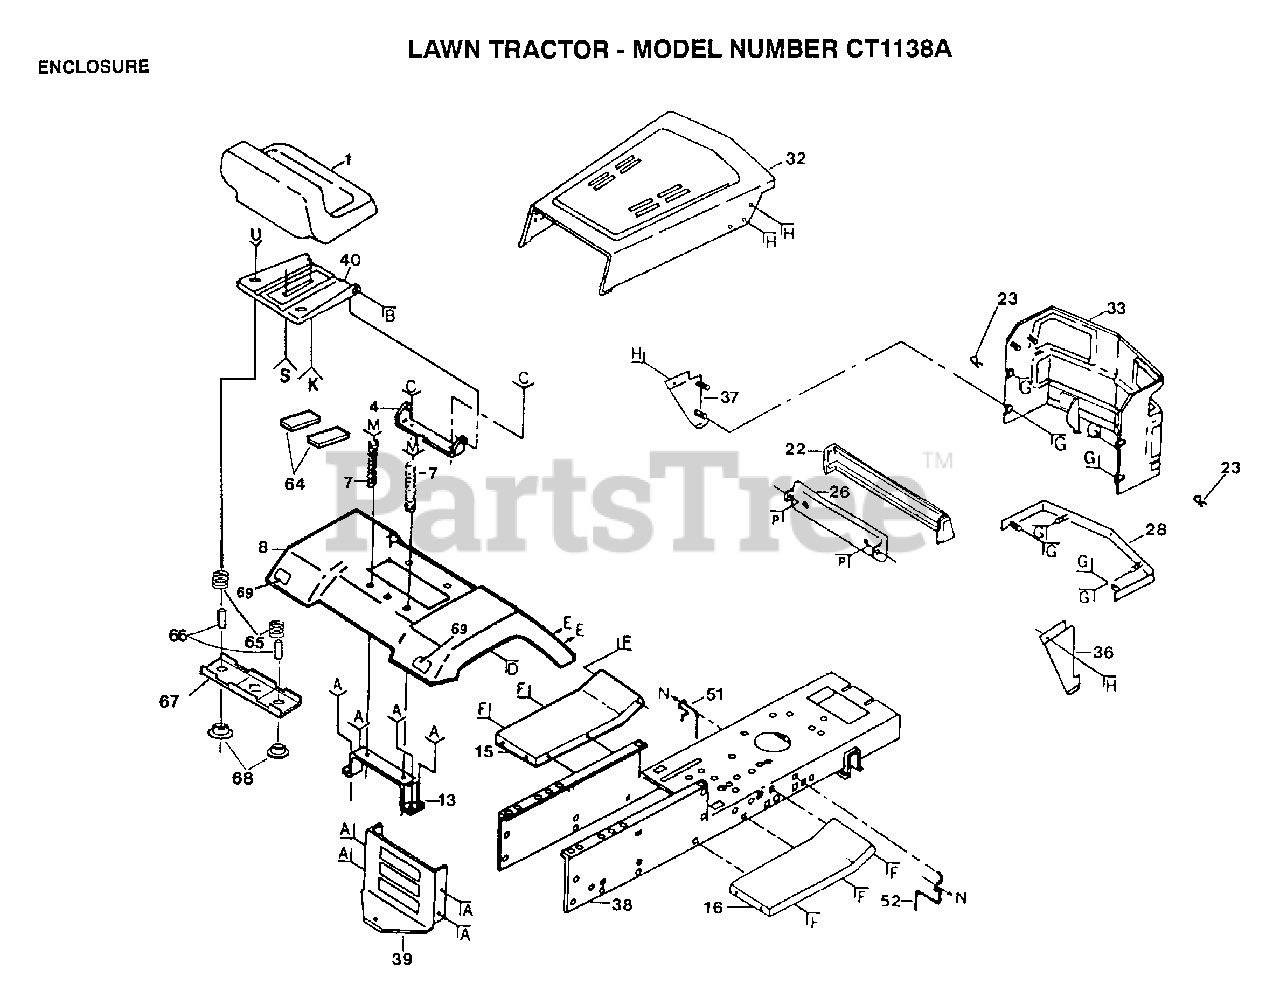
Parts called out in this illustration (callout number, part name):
7	SPRING COMPRESSIO
15	FOOTREST LH T
16	FOOTREST RH T
23	SPRING.RETAINER
28	"STRAP,GRILL T"
36	"PANEL,SIDE RH T"
37	"PANEL,SIDE LH T"
38	CHASSIS ASS'Y
51	BELT GUIDE
52	BELT GUIDE
64	STRIP FORM
65	SPRING COMPRESSED
66	SPACER SPLIT
67	BRKT SWITCH
68	BUSHING
69	REFLECTOR-TAIL YT
